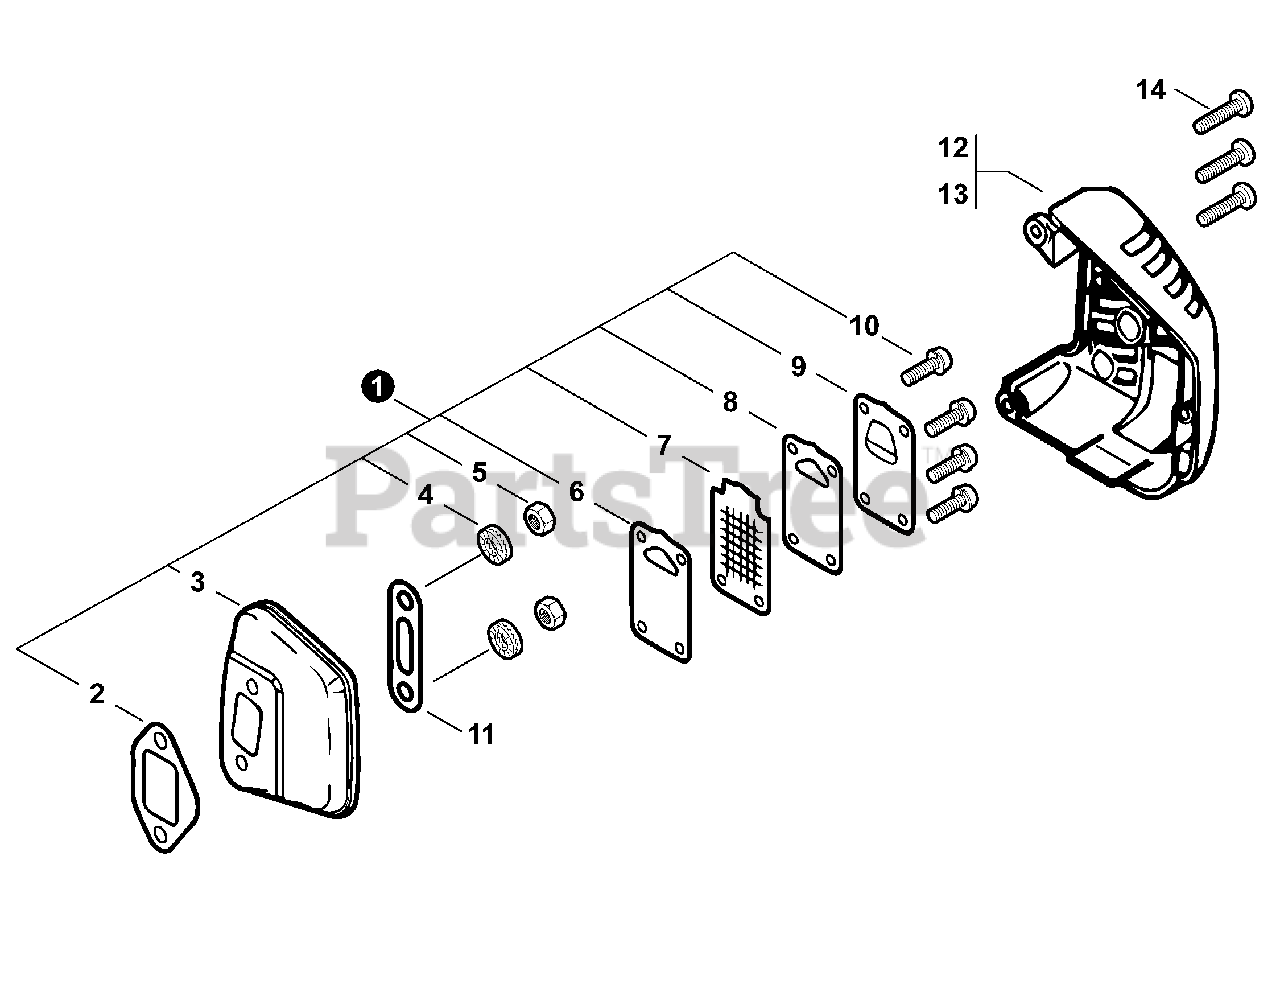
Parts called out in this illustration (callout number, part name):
1	MUFFLER KIT
2	GASKET, EXHAUST
3	MUFFLER
5	NUT M5
6	GUIDE, EXHAUST
7	SCREEN, SPARK ARRESTER
8	GASKET, EXHAUST
9	OUTLET, EXHAUST
10	SCREW 4×10
11	PLATE, EYE
12	COVER, MUFFLER - GRAY
13	COVER, MUFFLER - ORANGE
14	SCREW 4×16
